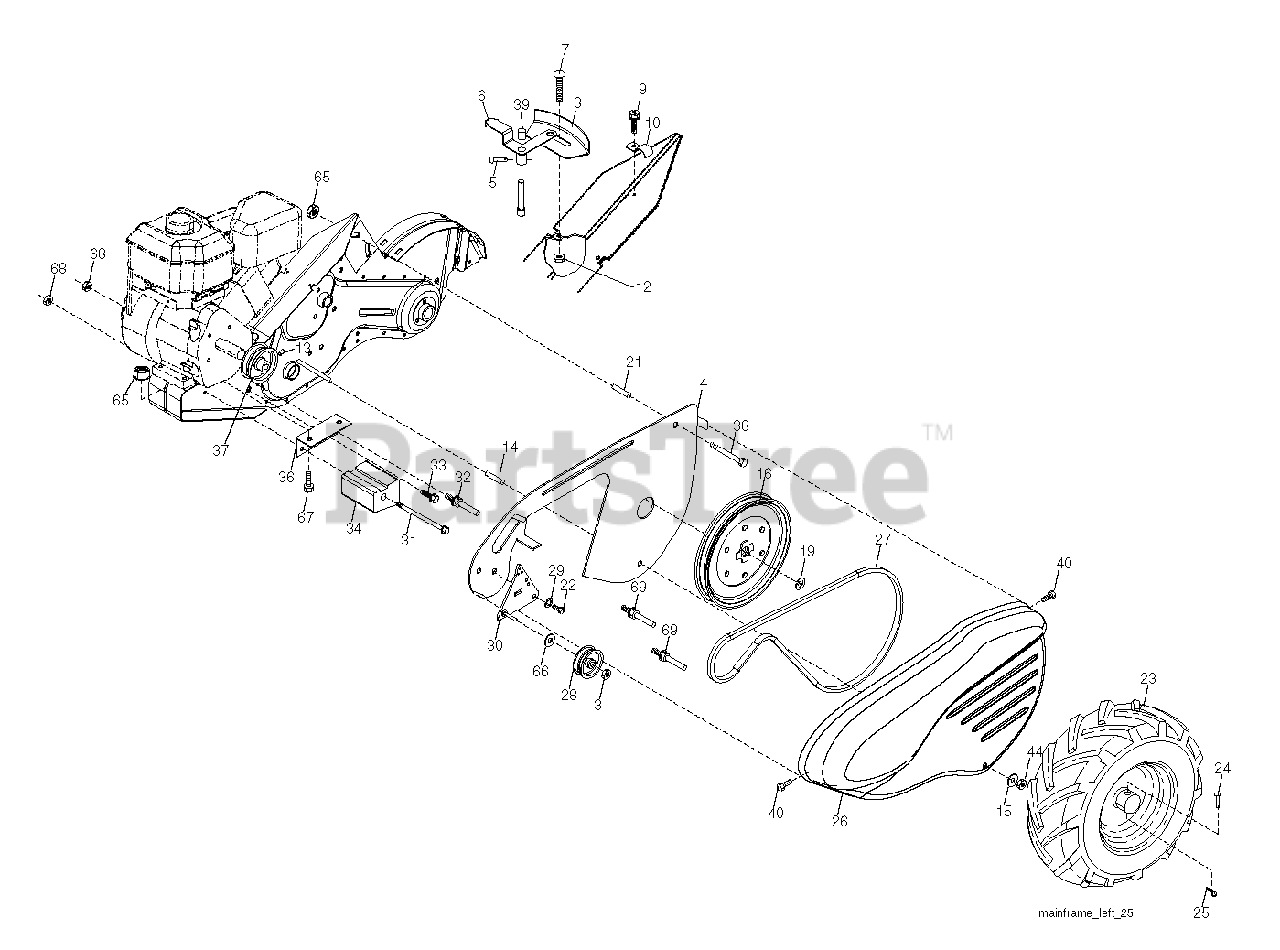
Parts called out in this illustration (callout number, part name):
3	LOCKNUT
5	PIN.SPIROL.FLARED
6	LEVER ASM CRT
8	PANEL.INDICATOR.SHIFT.BLACK
10	CLIP.PLATED
12	NUT
13	SET SCREW
14	SPACER-SPLIT.327 X .42
15	WASHER.FLAT.34X1.38X22
16	SHEAVE, TRANSMISSION
19	RETAINING RING LT
21	SPACER SPLIT
24	RIVET,DRILLED
27	V-BELT
28	PULLEY-IDLER TI
29	KLIP RING
30	BRACKET.IDLER.TILL.STUD.1.50
31	BOLT.FIN.HEX.3/8-16UNC X 11.5
32	SHIFT ARM CRT
33	BOLT
34	COUNTERWEIGHT.RH
36	COUNTERWEIGHT.LH
37	ENGINE PULLEY
39	CAP.PLUNGER.BLACK
40	SCREW.HEX.WSH.SLT.#10-24X.50
44	NUT.71038.31-18.HEX.NYLOCK
65	LOCKNUT-FLANGE 5/16-18
67	BOLT
69	WASHER
